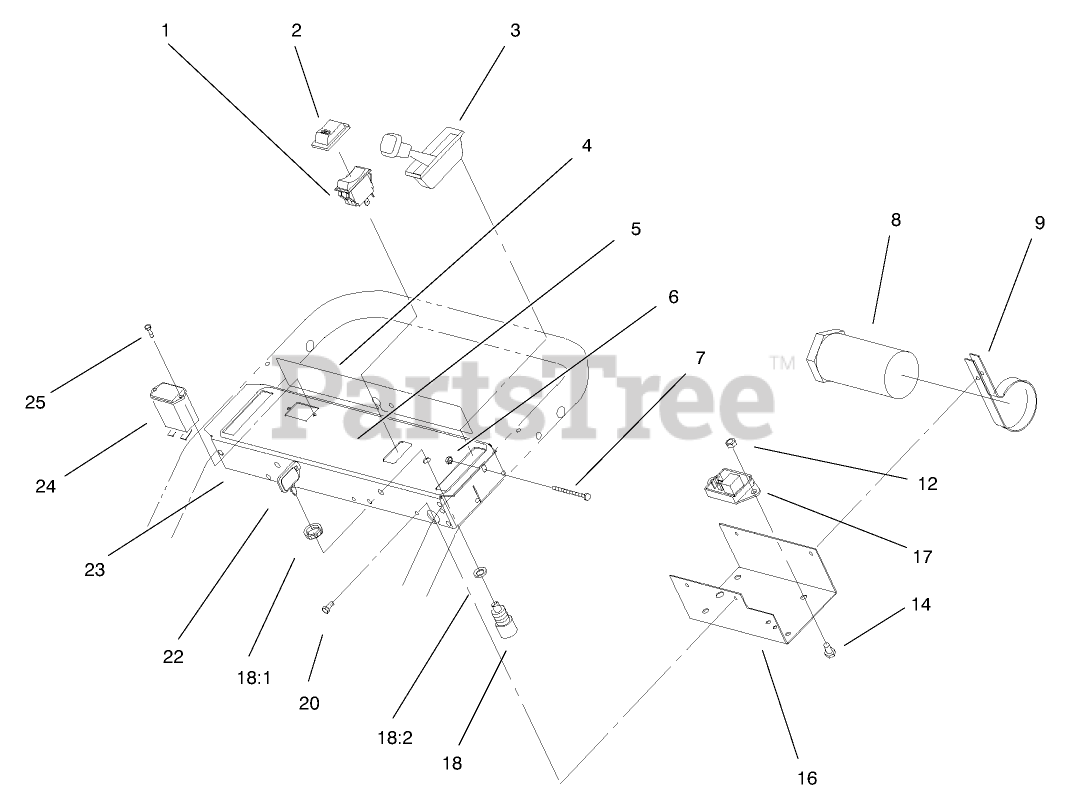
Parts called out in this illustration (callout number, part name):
1	SWITCH
2	BOOT-SWITCH
3	CONTROL-THROTTLE
4	DECAL-WARNING
5	DECAL - CONTROL PANEL
6	NUT-LOCK, NI
7	SCREW-SHH
8	TUBE-MANUAL
9	CLAMP-R
12	NUT-LOCK, NI
14	SCREW-HH
16	PANEL-BOTTOM
17	MODULE-DELAY
18	SWITCH-STARTER
18:1	NUT-HH
18:2	WASHER-TOOTH, INTERNAL
20	SCREW-HWHTF
22	KEY-IGNITION
23	PANEL - CONTROL
24	HOURMETER
25	SCREW-HWH
